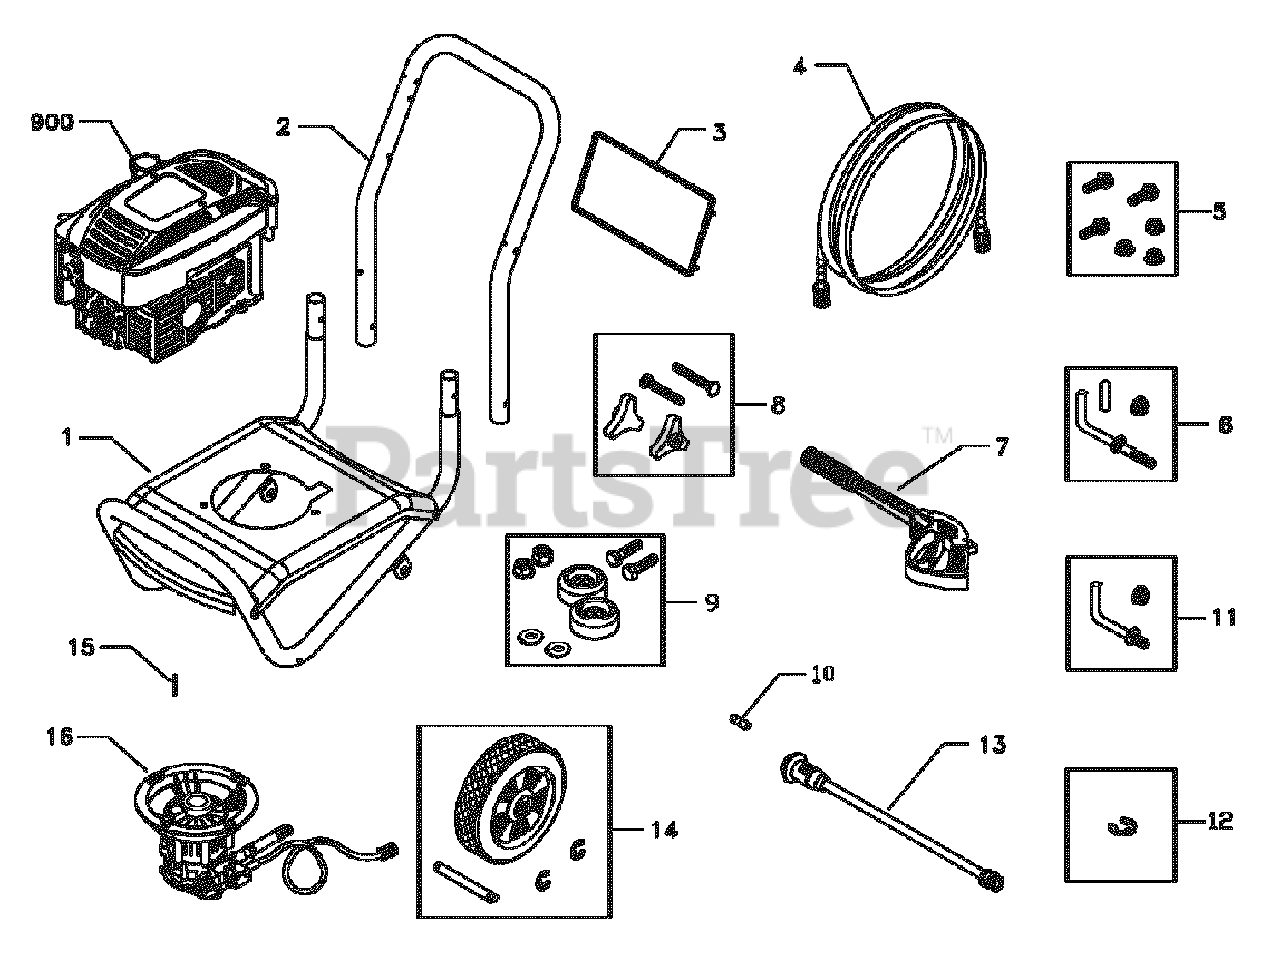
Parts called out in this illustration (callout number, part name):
1	BASE
3	BILLBOARD
4	HOSE
5	KIT, Pump Mounting Hardware
6	KIT, Hook
8	KIT, Handle Connector
9	KIT, Vibration Mount
10	ORIFICE
11	KIT, Hook
12	KIT, E-Ring
13	WAND, Adjustable Nozzle
14	KIT, Wheel
16	ASSY, Pump
900	§ ENGINE
